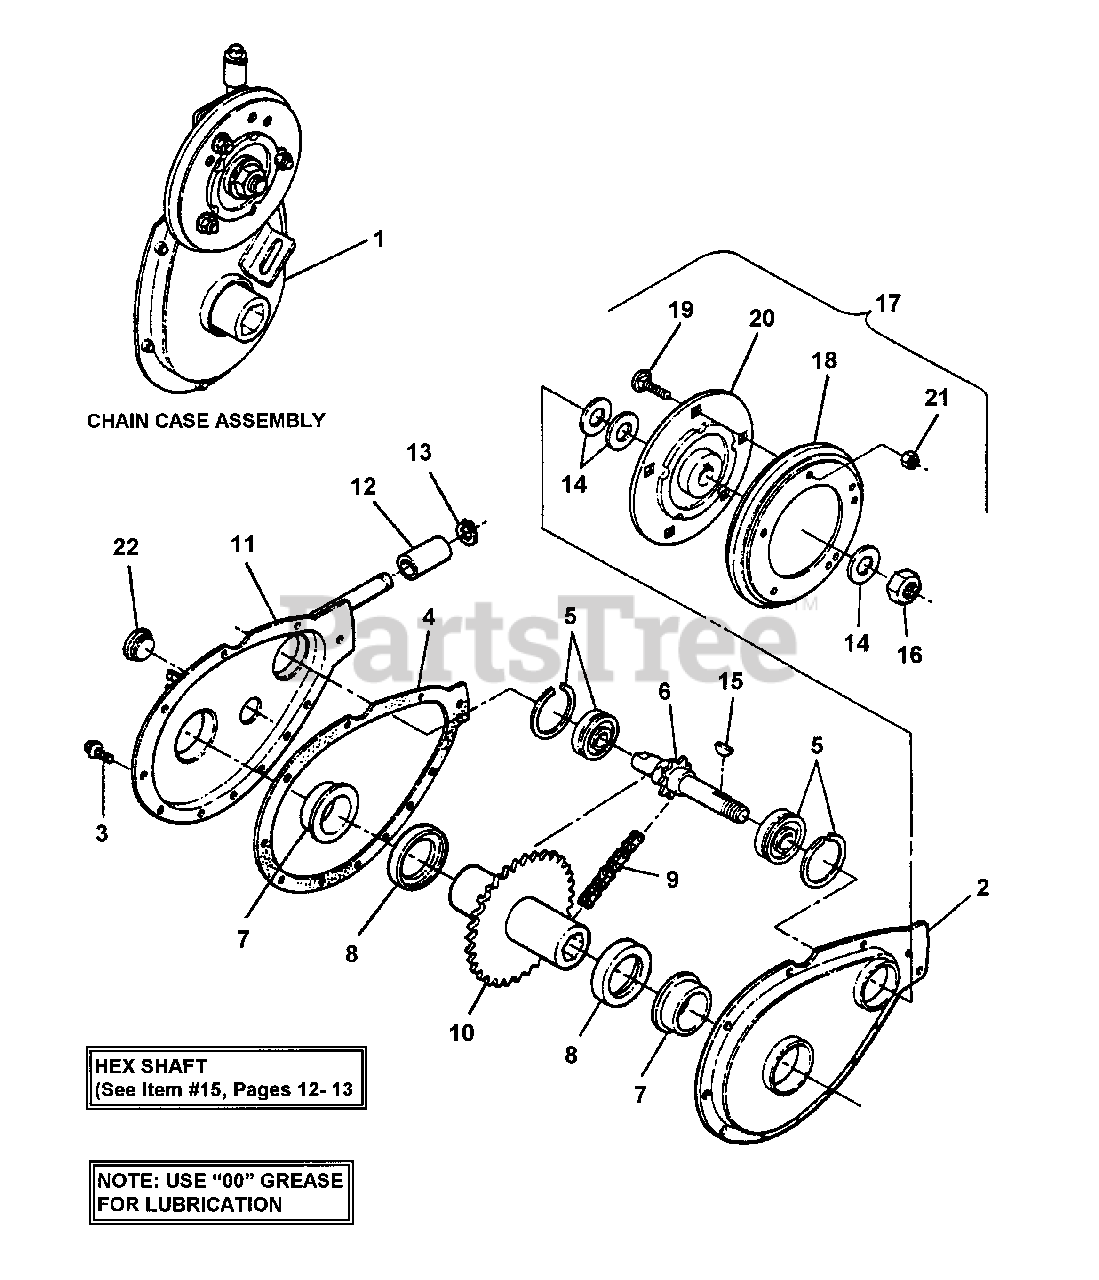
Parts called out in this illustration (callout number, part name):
1	ASSEMBLY, Chain Case
2	COVER, Sprocket
3	SCREW, #10-24 x 1/2" Hex Washer Self-Tap (Torx)
4	GASKET
5	BEARING, Ball
6	ASSEMBLY, Shaft & Sprocket
7	BUSHING
8	WASHER, Thrust
9	CHAIN
10	ASSEMBLY, Hub & Sprocket
11	CHASE, Sprocket
12	ROLLER
13	RING, 1/2" External Snap (Heavy Duty)
14	WASHER, Belleville
15	KEY, 1/8 x 5/8" Woodruff
16	NUT, 5/8-18 Hex Center Lock Jam
17	ASSEMBLY, Drive Disc
18	DISC, Driven (R/B 7018782)
19	BOLT, 5/16-18 x 1/2" Short Neck Carriage, Grade 5
20	HUB
21	NUT, 5/16-18 Hex Flange Lock, Grade 5
22	PLUG
